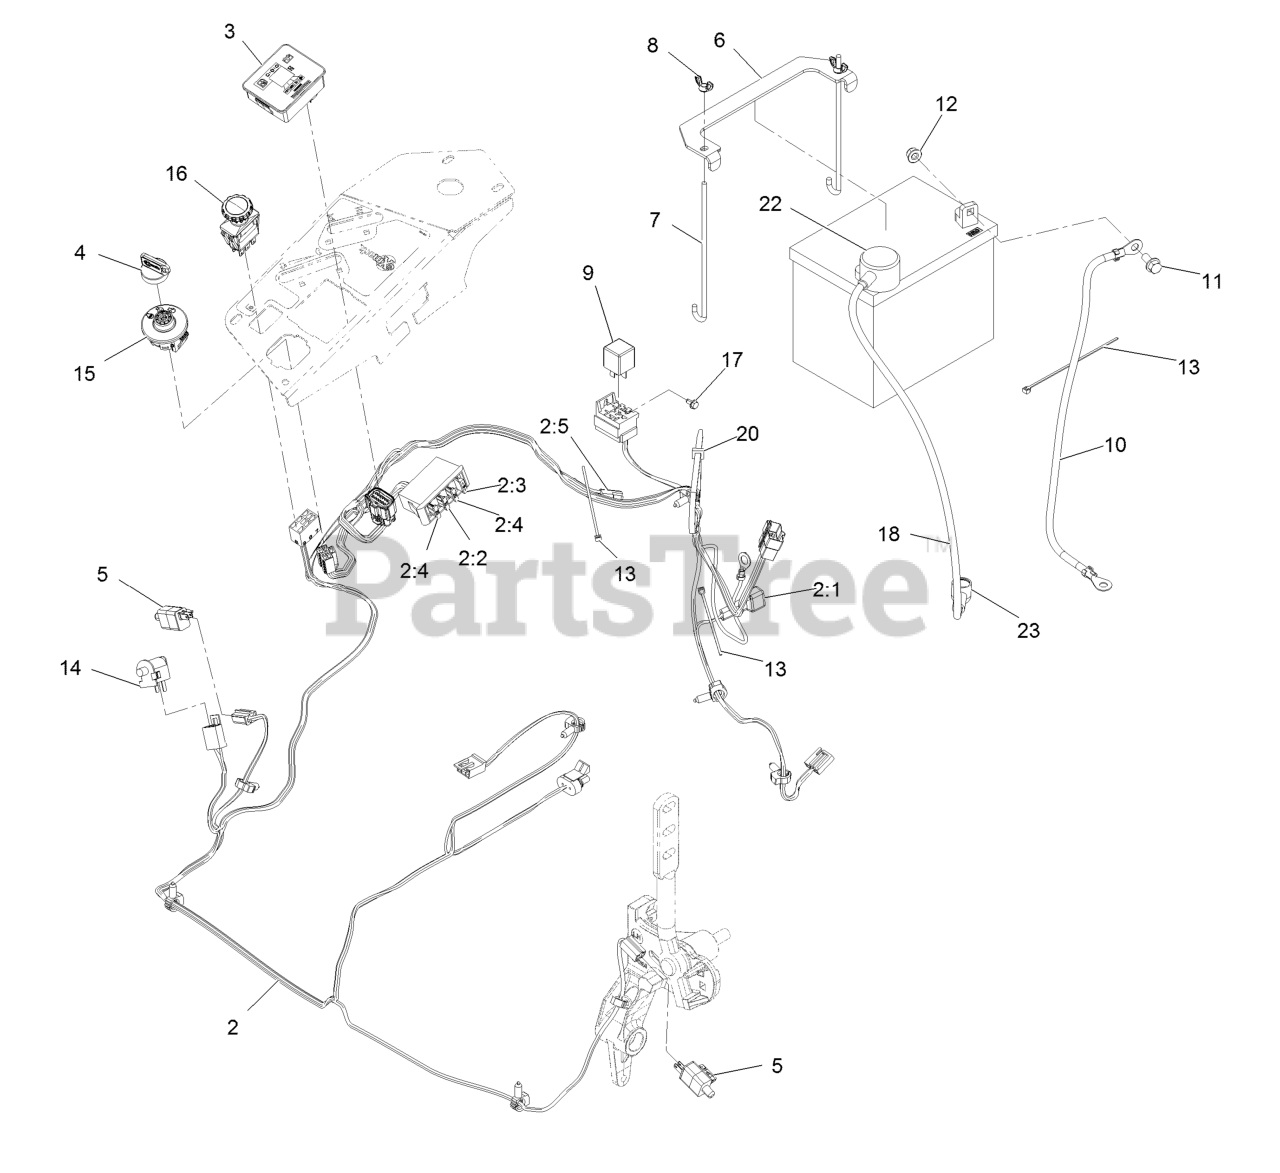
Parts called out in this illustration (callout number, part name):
2	Harness-Wire, Main
2:2	Fuse-Blade, 10 Amp
2:3	Fuse-Blade, 15 Amp
2:4	Fuse-Blade, 25 Amp
2:5	Cap-Plug
3	Fuel/Hour Meter ASM
4	Key-Ignition
4	Key-Exmark Logo
6	Strap-Tie Down, Battery
7	Bolt-Holddown
8	Wingnut-Nyloc 1/4-20
9	Relay-12Vdc 40 Amp
10	Cable-Battery, Negative
11	Screw-HH Flg 5/16-18 X 3/4
12	Nut-Nyloc 5/16-18 Flg
13	Tie-Cable 5 1/2 (Small)
15	Switch-Ignition
16	Switch-PTO, 10 Amp
17	Screw-HWH #10-24 X 3/8
18	Cable-Battery, Positive
20	Tie-Cable 7 15/16 (Large)
22	Insulator-Battery
23	Insulator-Solenoid
